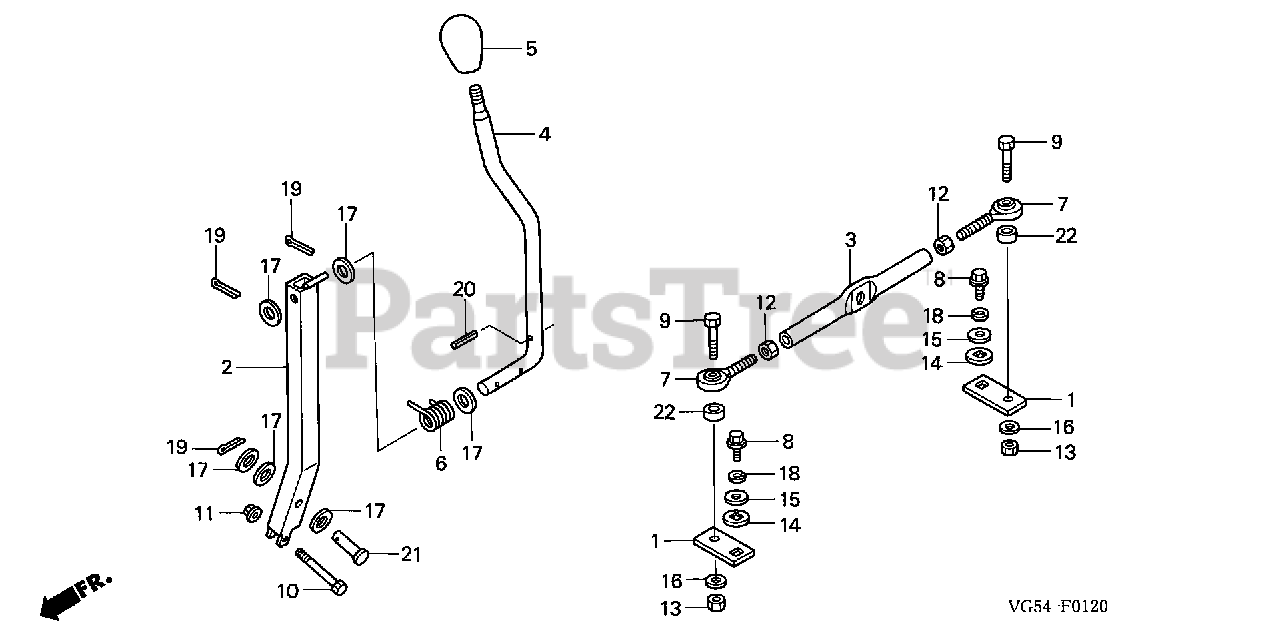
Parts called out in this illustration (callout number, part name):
1	ARM, CHANGE
2	ARM, CHANGE
3	ROD, GEARSHIFT
4	LEVER, CHANGE
5	GRIP, CHANGE LEVER
6	SPRING, CHANGE LEVER
7	END, ROD (5/16")
8	BOLT, FLANGE (1/4")
9	BOLT, HEX. (5/16-18X1 1/2")
10	BOLT, HEX. (3/8-16X2")
11	NUT, CENTERLOCK (3/8-16)
12	NUT, HEX. (5/16"-24)
13	NUT, CENTERLOCK (5/16"-18")
14	WASHER, CHANGE ARM
15	WASHER, FLAT (1/4")
16	WASHER, FLAT (5/16")
17	WASHER, FLAT (3/4")
18	WASHER, LOCK (1/4")
19	PIN, COTTER (1/8"X1 1/4") (NOT AVAILABLE)
20	PIN, SPRING LOCK (1 /4"X1 1/4")
21	PIN, CLEVIS (3/4"- 2 3/4")
22	COLLAR (5/16")
